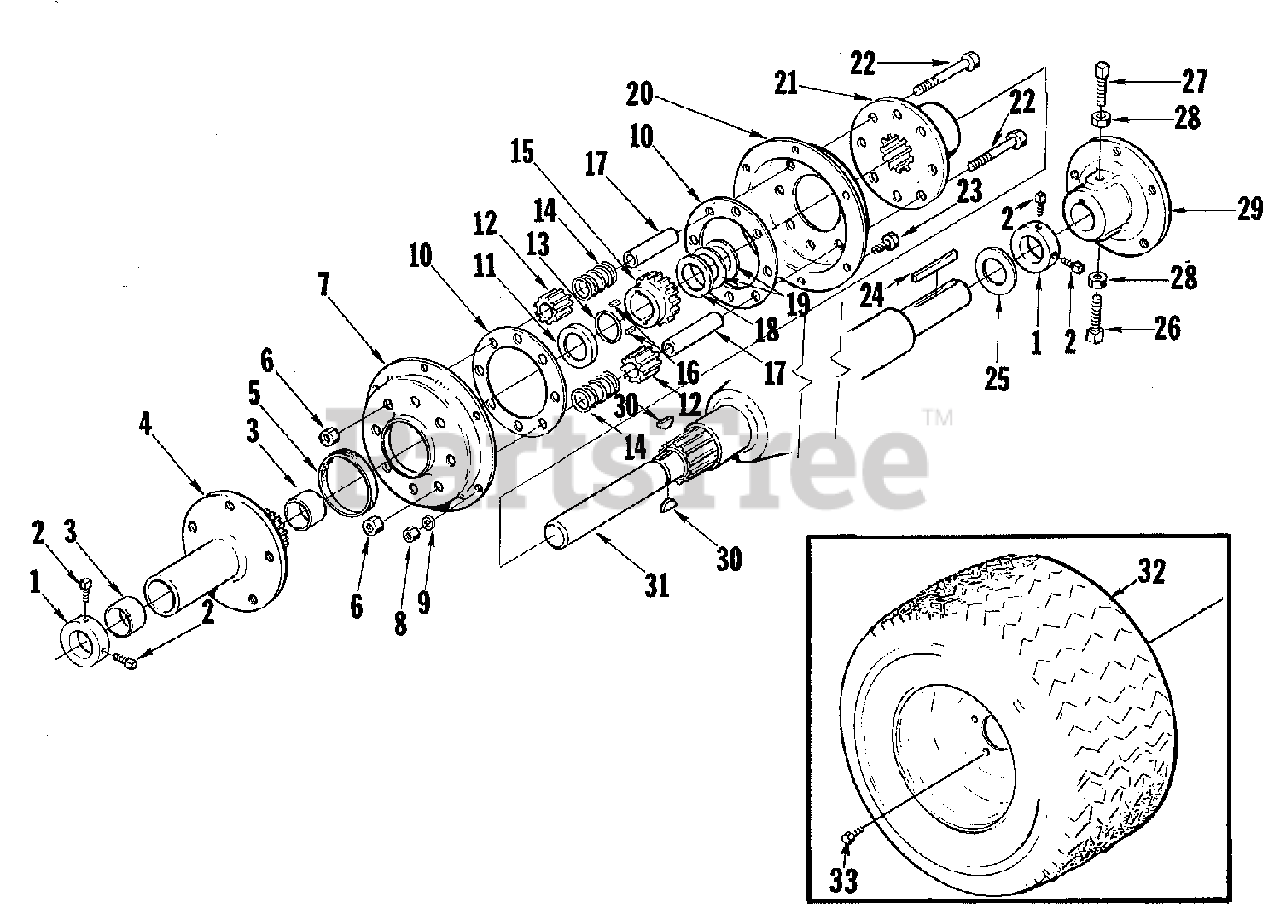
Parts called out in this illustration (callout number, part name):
1	COLLAR, Axle
2	SET SCREW, Square Head, 5/16-18 x 3/8
4	HUB ASSEMBLY, Wheel, R.H.
5	SEAL, Differential Cover
6	NUT, Hex Lock, 3/8-16
7	COVER, Differential
8	NUT, Hex Fin, 1/4-20
9	LOCKWASHER, 1
10	RING, Spacer
11	WASHER, Axle
12	PINION, Differential
13	RING, Retaining
15	GEAR, Differential
17	SPINDLE, Pinion Differential
18	WASHER, Axle
19	WASHER, Axle
20	COVER, Differential
21	CARRIER, Differential
22	SCREW, Hex Head Cap, 3/8-16 x 2-1/2
23	SCREW, Hex Head Cap, 1/4-20 x 5/8
26	SCREW, 3/8-16 x 1-1/2
28	NUT, Jam, Hex, 3/8-16
29	HUB, Wheel, L.H.
32	WHEEL & TIRE, Rear (T-10)
32	WHEEL & TIRE, Rear (T-12, T-15)
